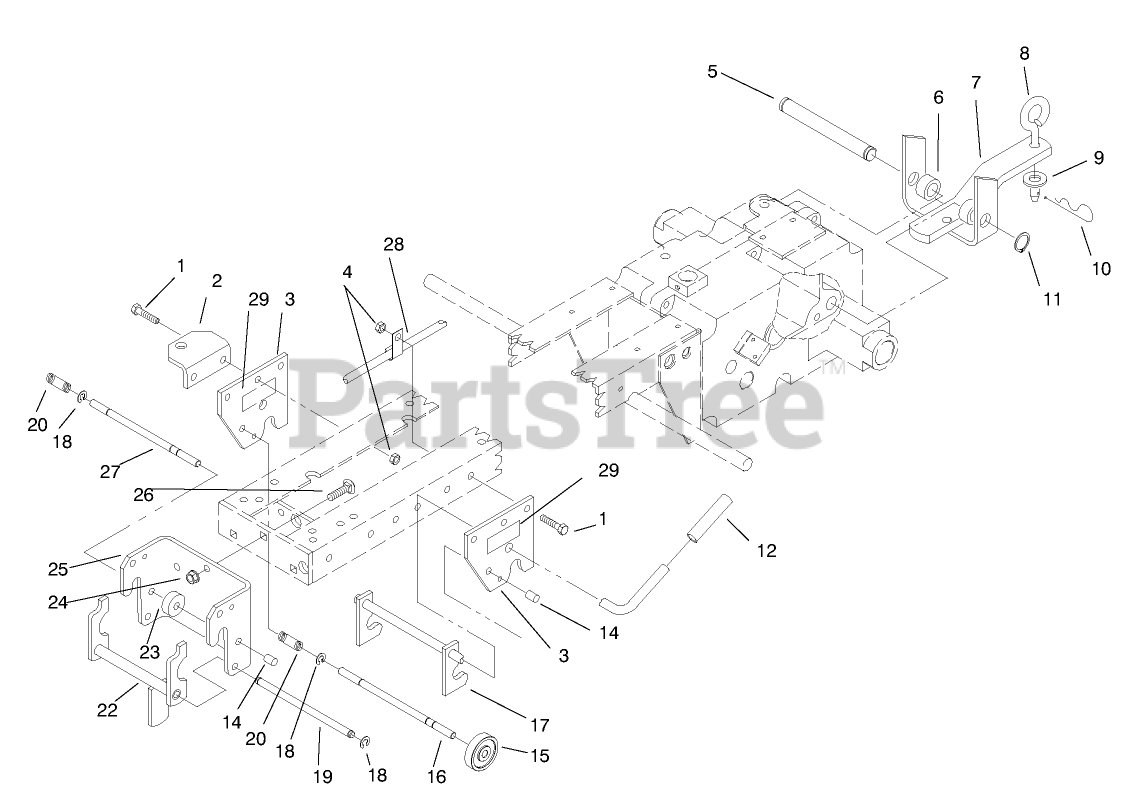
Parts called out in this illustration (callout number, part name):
1	SCREW-HH
2	SUPPORT
3	PLATE-HITCH
4	NUT-HEX
5	PIN-STATIONARY HITCH
6	SPACER
8	PIN-TOOL
9	WASHER-FLAT
10	PIN-HAIR
11	E-RING
12	GRIP
14	CAP-ROD, PLUNGER
16	ROD-LOCK
17	MID HITCH ASM
18	RING-RETAINING
19	ROD-LATCH PIVOT
20	SPRING
22	LATCH
24	NUT-LOCK, NI
25	HITCH-FRONT
26	BOLT-CARR
27	ROD-LOCK
28	CLIP
29	DECAL-ATTACH A-MATIC
